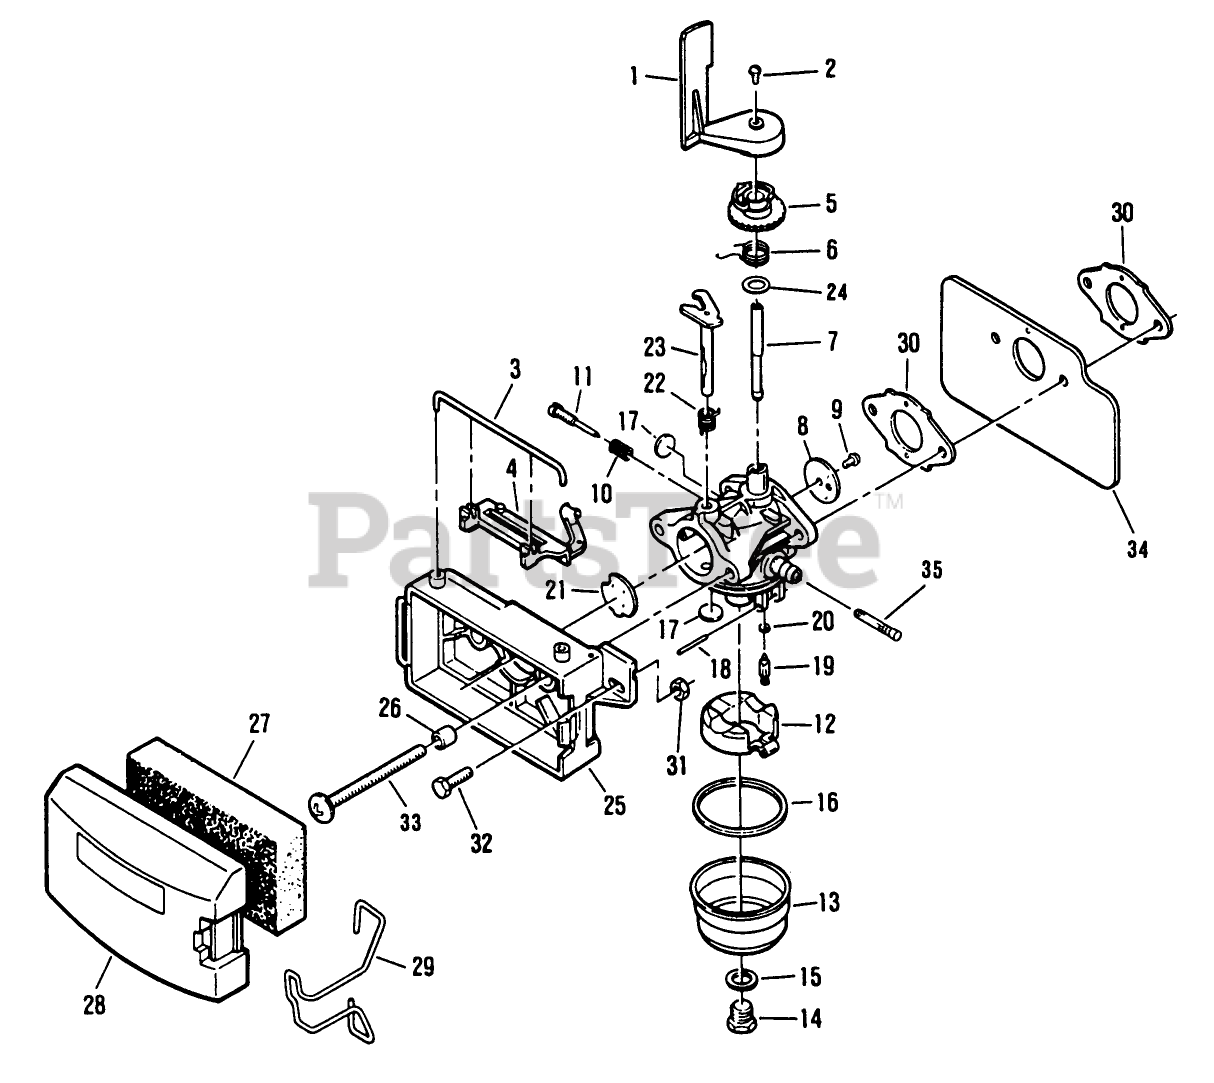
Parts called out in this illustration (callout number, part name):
1	P-BULB LAV-RUB
1	AIR VANE F
2	SCREW F
3	RETAINER
4	LOCKNUT S
5	COLLAR A/VAVE F
6	THROTTLE SPR E
7	Shaft-Throttle
8	Valve-Throttle
9	Screw-Throttle Valve
10	Spring-Idle Needle
11	Needle-Idle
13	Bowl-Fuel
14	Screw-Bowl Retainer
15	Gasket-Bowl Retainer
16	Gasket-Fuel Bowl
17	Plug-Welch
18	Shaft-Float
19	Valve-Inlet Needle
20	Seat-Valve
21	Valve-Choke
22	Spring-Choke Return
23	Shaft-Choke
24	WASHER VF
26	SPACER
29	RETAINER-COVER, FILTER
30	GASKET CARB S
32	SCREW
33	SCREW
35	SCREEN FUEL PITTS
